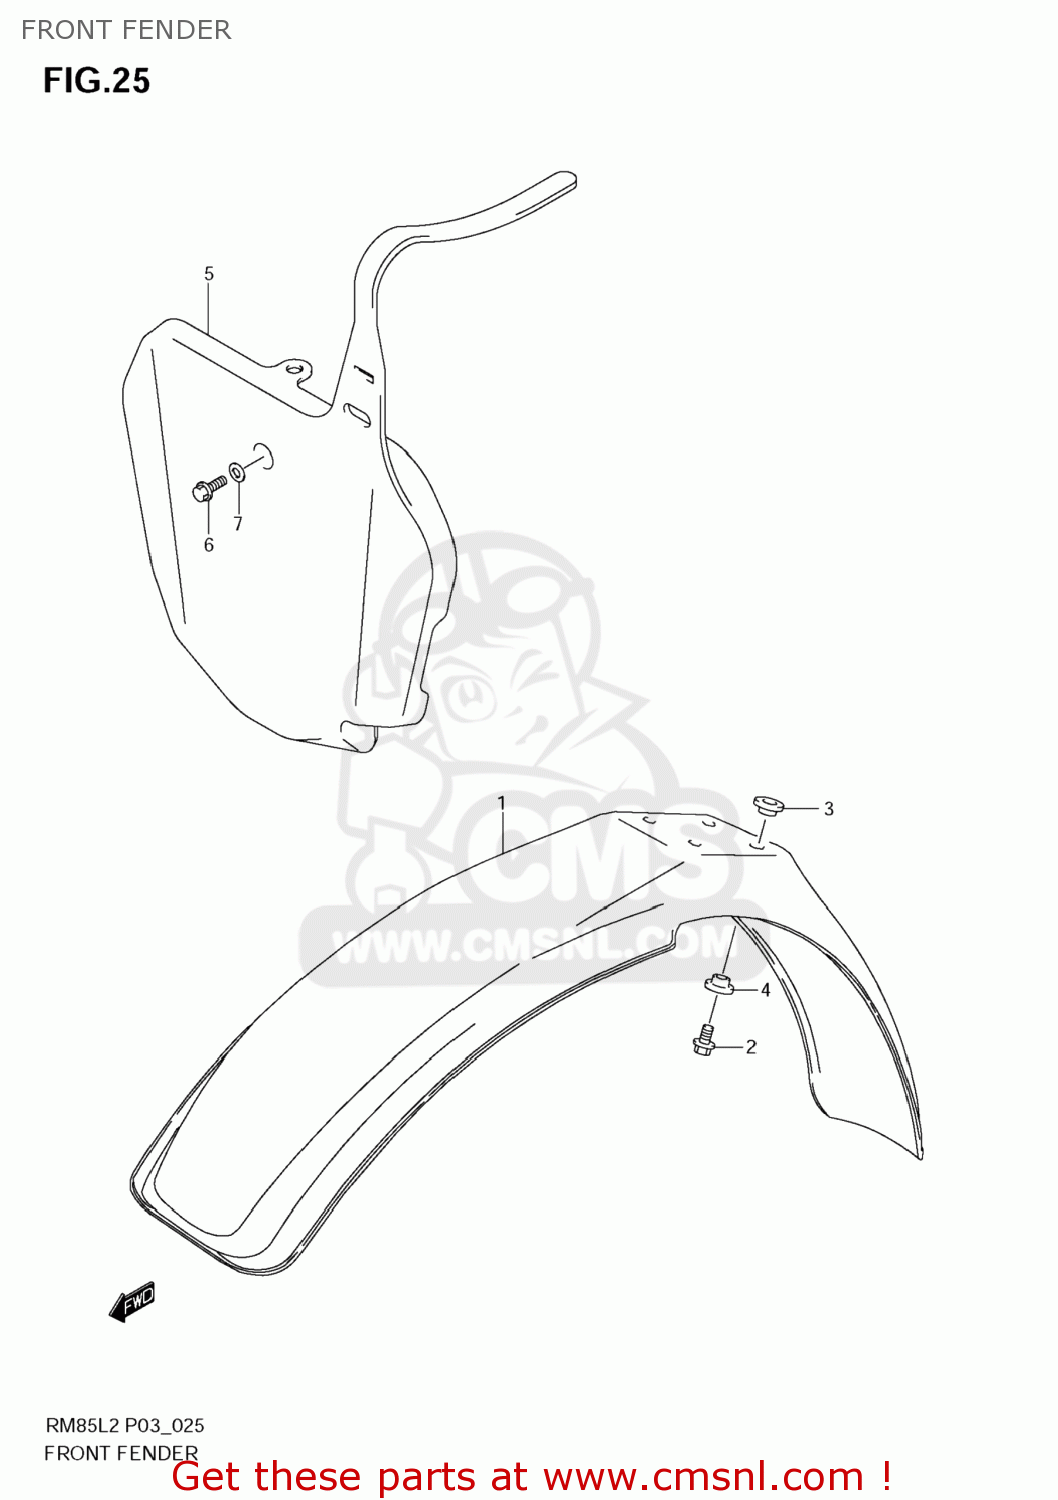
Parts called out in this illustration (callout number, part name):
1	FENDER,FR
2	BOLT
3	WASHER
4	WASHER
5	PLATE,NUMBER FR
6	BOLT
7	WASHER(6.5X14X1.6)
